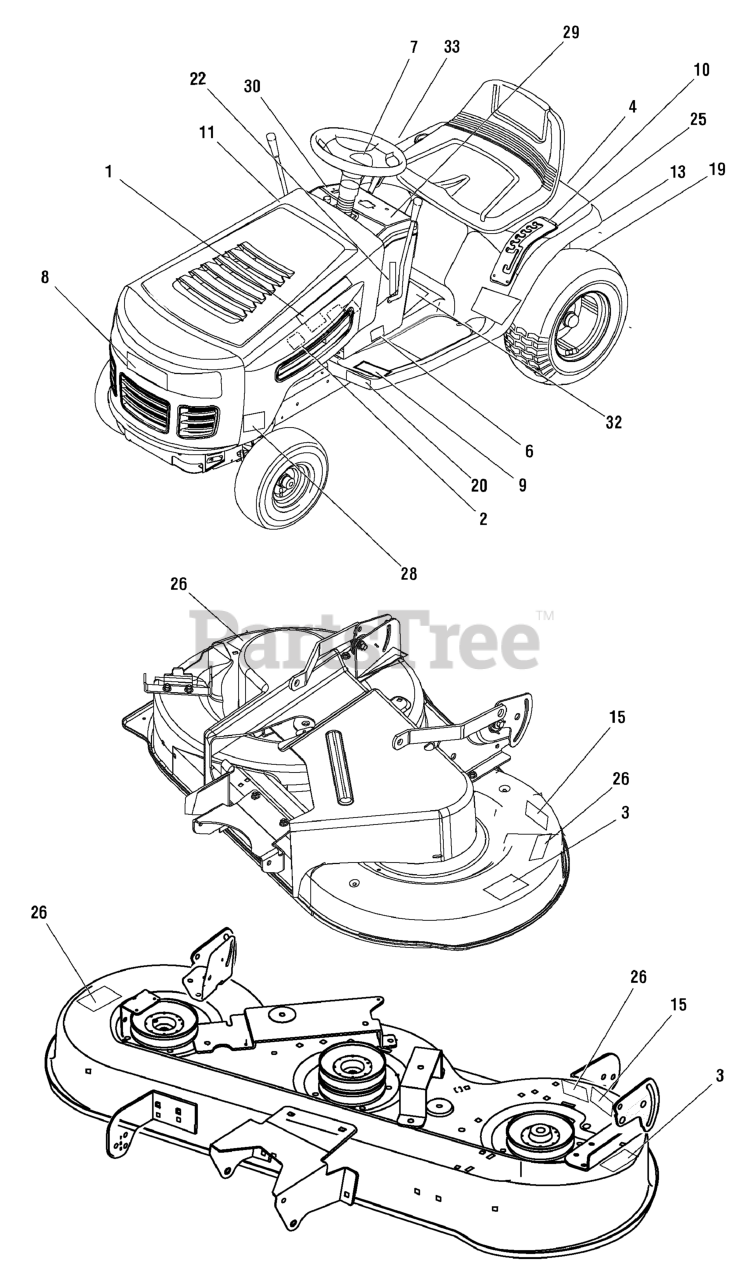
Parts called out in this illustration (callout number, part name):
1	DECAL, Logo, Side Hood
2	DECAL, Model, Side Hood
3	DECAL, Deck Width, 107 cm, 42 in
3	DECAL, Deck Width, 117 cm, 46 in
3	DECAL, Deck Width, 96 cm, 38 in
4	DECAL, Yard King, Rear
6	DECAL, 12.5HP I/C
6	DECAL, 15.5 HP I/C
6	DECAL, 22 HP Intek
6	DECAL, 17.5HP Intek
7	DECAL, Steering Wheel
8	DECAL, Yard King, Grille
9	DECAL, Belt/ Clutch
10	DECAL, Height of Cut
11	DECAL, Cut Height, 7 Position
13	DECAL, Roll Release
15	DECAL, No Step
19	DECAL, Weight Limitation
20	DECAL, Drive Pedal
22	DECAL, Gas Gauge
22	DECAL, Fuel Gauge Long
25	DECAL, Deck Level
26	DECAL, Deck Symbols, International
27	DECAL, Warning, Pinch Point
28	DECAL, Heat Shield Warning
29	DECAL, Dash / Symbols X-W Styles
30	DECAL, Dash/ Symbols
31	DECAL, Dash/ Symbols
32	DECAL, Tunnel Cover Warnings
33	DECAL, 5 Speed
